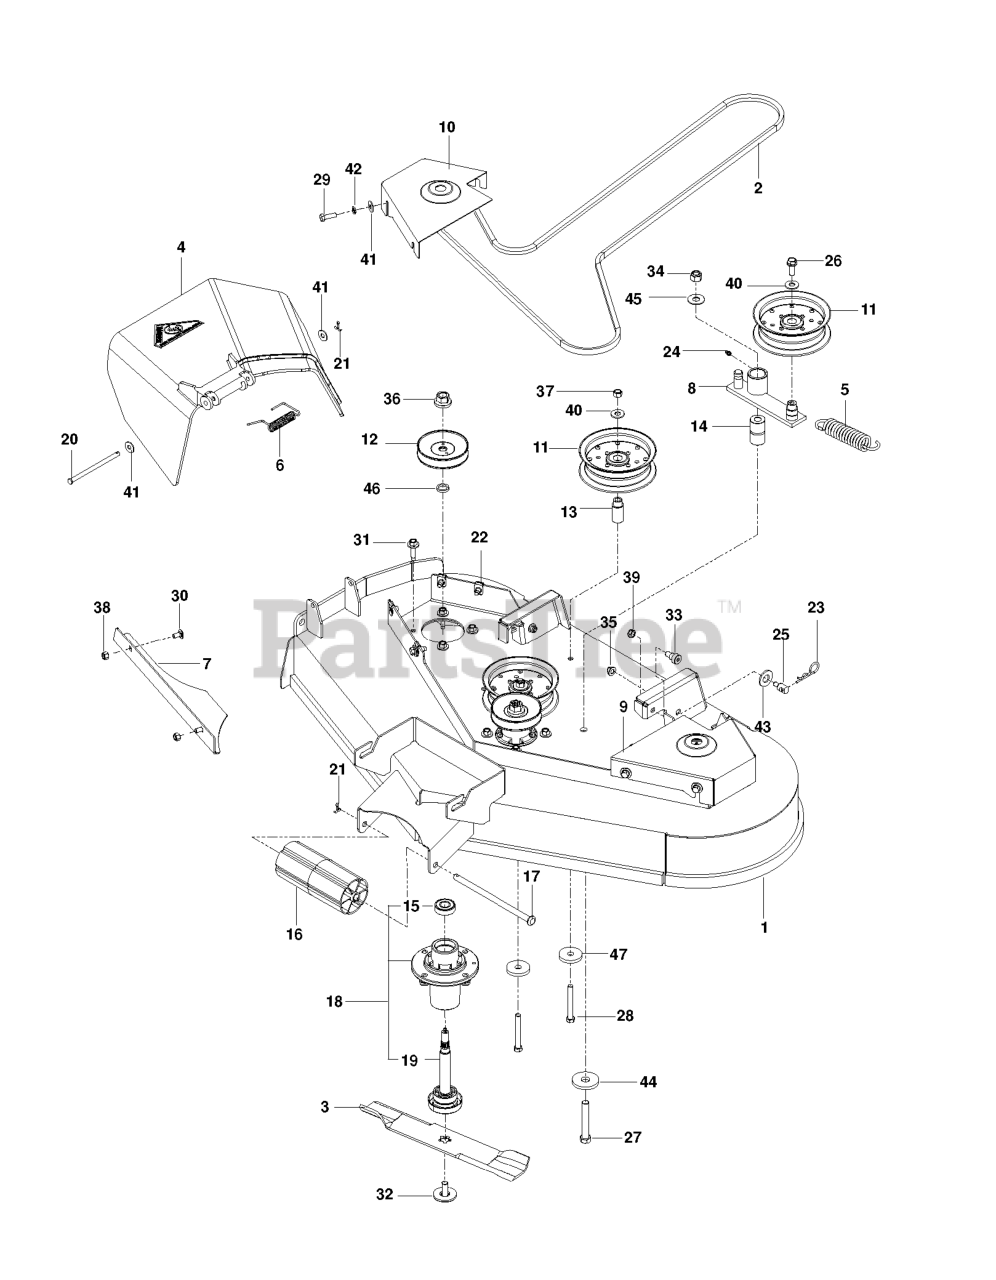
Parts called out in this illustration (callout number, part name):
1	DECK SVC W/DECALS 42 RZ ORANGE
3	BLADE, 14 5/8"
4	DISCHARGE CHUTE 42"
6	SPRING - TORSION
7	CONFINEMENT.PLATE.42".BLACK
9	BELT SHIELD, LEFT 42, ORG
10	BELT SHIELD, RIGHT 42, ORG
11	PULLEY, IDLER
12	PULLEY, MADREL 3.70 OP
13	IDLER BUSHING
14	PIVOT BUSHING
16	NOSE ROLLER 48"
17	ROD.ROLLER.NOSE.NARROW.48"
18	MANDREL.DECK.ASSEMBLY
19	SHAFT ASM MANDREL
20	PIN-CLEVIS 5/16 DIA X 5.19 ZD
21	COTTER PIN
22	U-CLIP 5/16-18 NUT RETAINER
23	HAIRPIN #4
24	ZERK
25	STUD.FASTNER.W/ANTI-ROTATE
26	4CS 3/8C X 1 SERRATED HEAD
27	HCS 1/2C X 3 1/4
28	BOLT.HEX.FIN.3/8-16 X 3.GR5
29	BOLT.FIN.HEX.5/16-18UNC X 1.00
30	BOLT.CARR.5/16-18X5/8.SHORT
31	SCREW, WASHER HEAD
32	BOLT.WASHER.ASM.7/16-2
33	SB 3/8-16 X 3/8 SKT HD ZD
34	NUT 1/2-13 HEX NYLOC ZD
35	5/16-18 NYLOC FLANGE NUT
36	NUT.FLANGE.LOCK.TOP
37	NUT 3/8-16 NYLOC
38	NUT.71038.31-18.HEX.NYLOCK
39	NUT HEX 3/8-16 NYLON, THIN
40	RP WASHER 3/8 FLAT
41	WASHER.5/16.FLAT.STE.STD.
42	WASH.5/16.SLW.ZD
43	WASHER
44	WASHER, SUPPORT
45	WASHER 1/2 FLAT
46	WASHER.SPACER.MANDREL
47	SPINDLE WASHER
